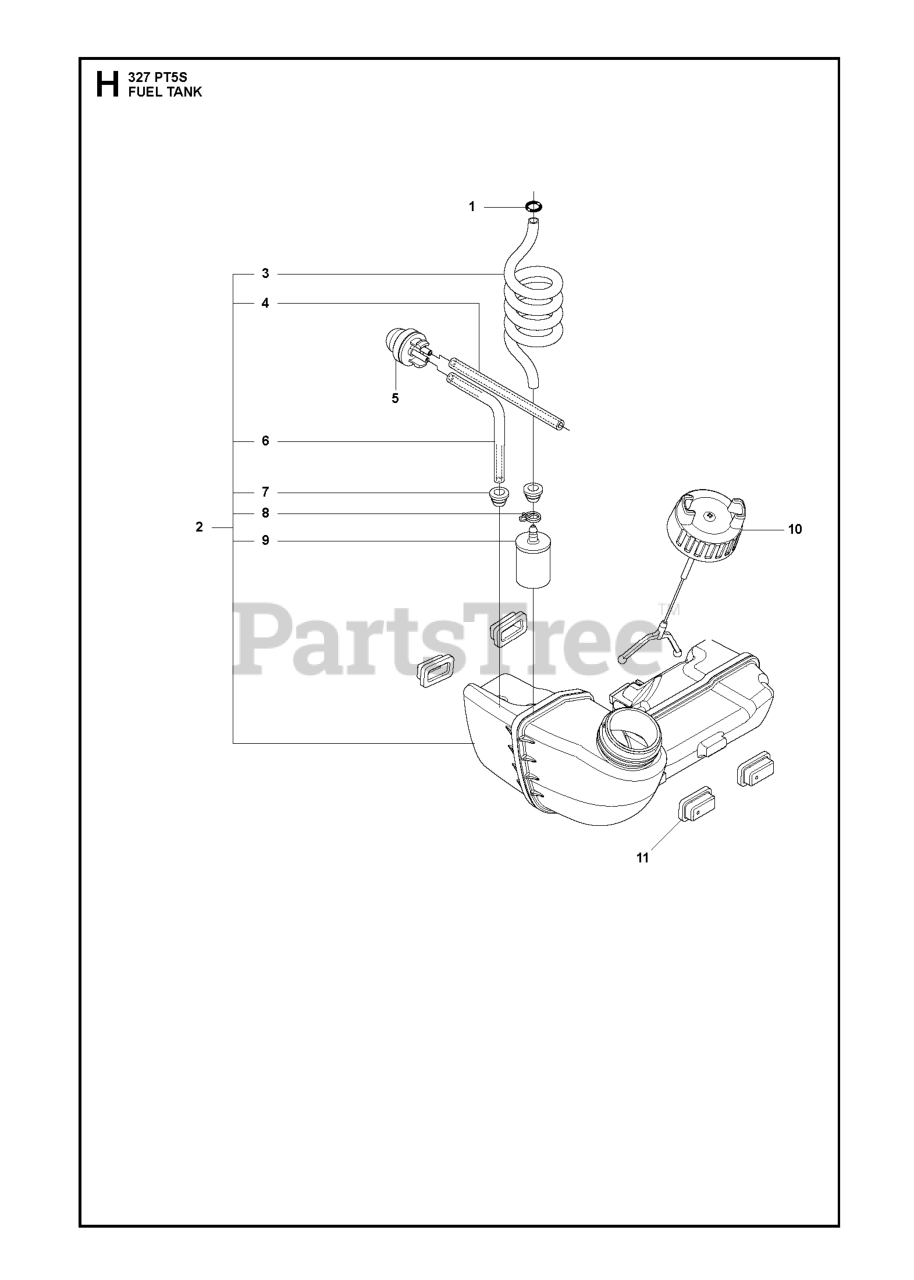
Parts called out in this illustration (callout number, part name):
2	RP FUEL TANK ASSY
3	FUEL HOSE
4	HOSE.FUEL L=102
5	AIR PURGE BUBBLE
6	HOSE.FUEL L=102
7	FUEL TANK BUSHING
8	HOSE CLAMP
9	RP FUEL FILTER
10	%FUEL CAP
